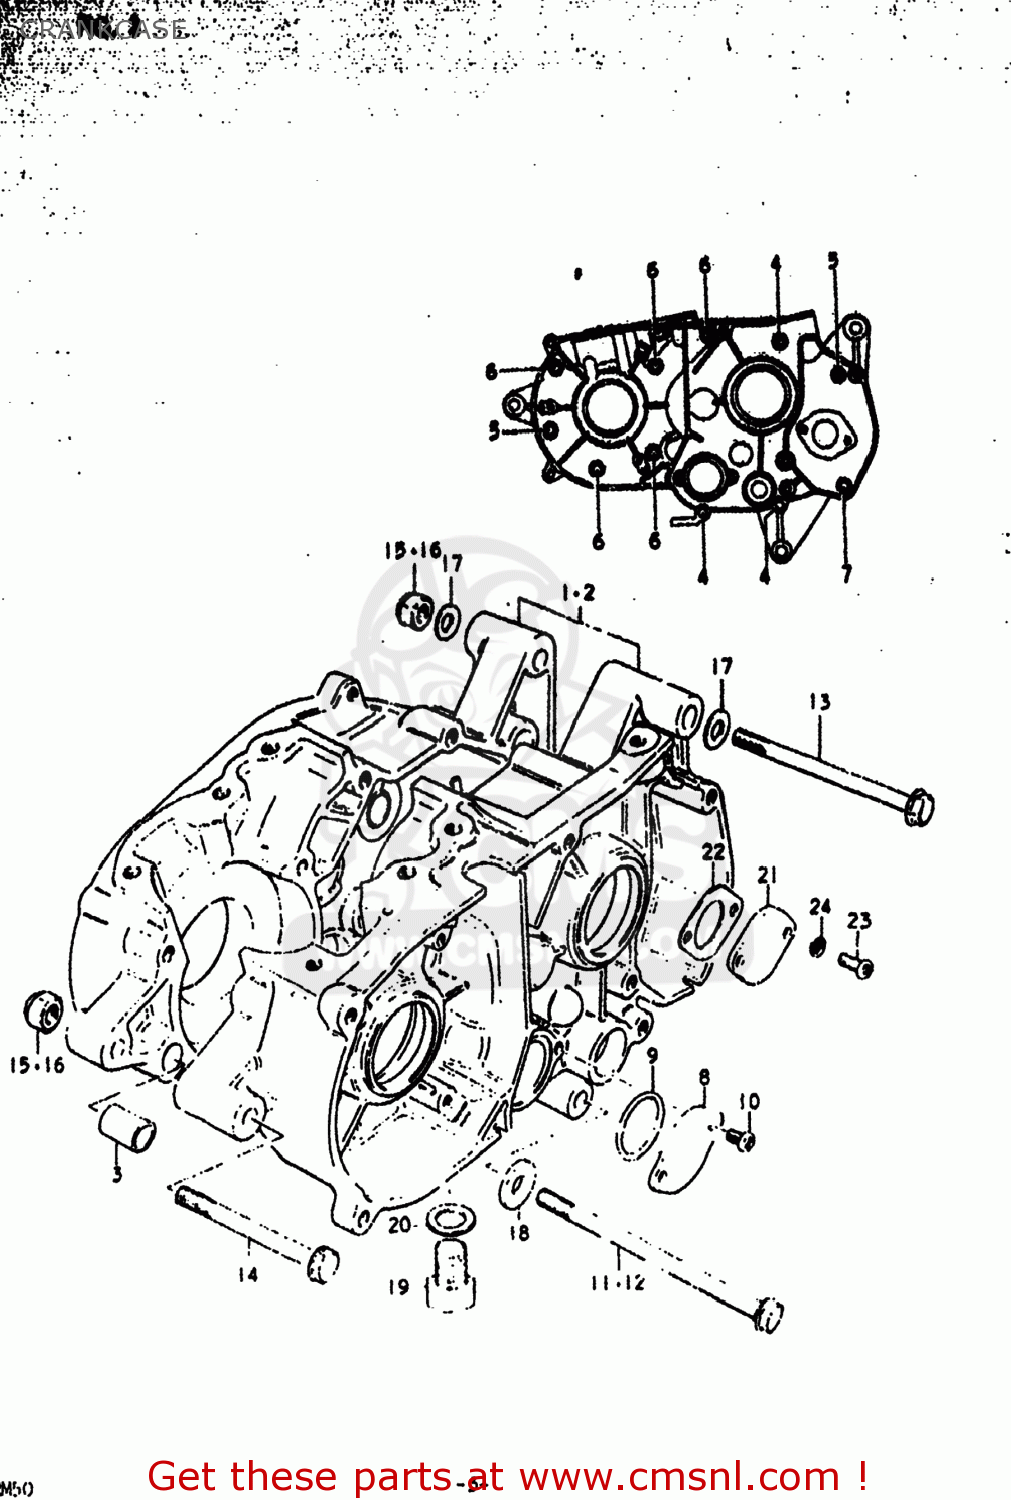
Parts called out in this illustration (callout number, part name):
1	CRANKCASE SET
2	PIN
3	SCREW
4	SCREW (6X45)
5	SCREW (6X35)
6	SCREW
7	CAP,GEAR SHIFT CAM PIVOT
8	O-RING (D:2.4 ID:26.2)
9	SCREW
10	BOLT
11	BOLT
12	BOLT
13	BOLT 8X75
14	NUT
15	NUT
16	WASHER
17	WASHER
18	BOLT 10X20
19	GASKET(10X14X3.6) (NAS)
20	CAP,OIL PUMP DRIVE SHAFT
21	GASKET,OIL PUMP (MCA)
22	SCREW
23	LOCK WASHER
